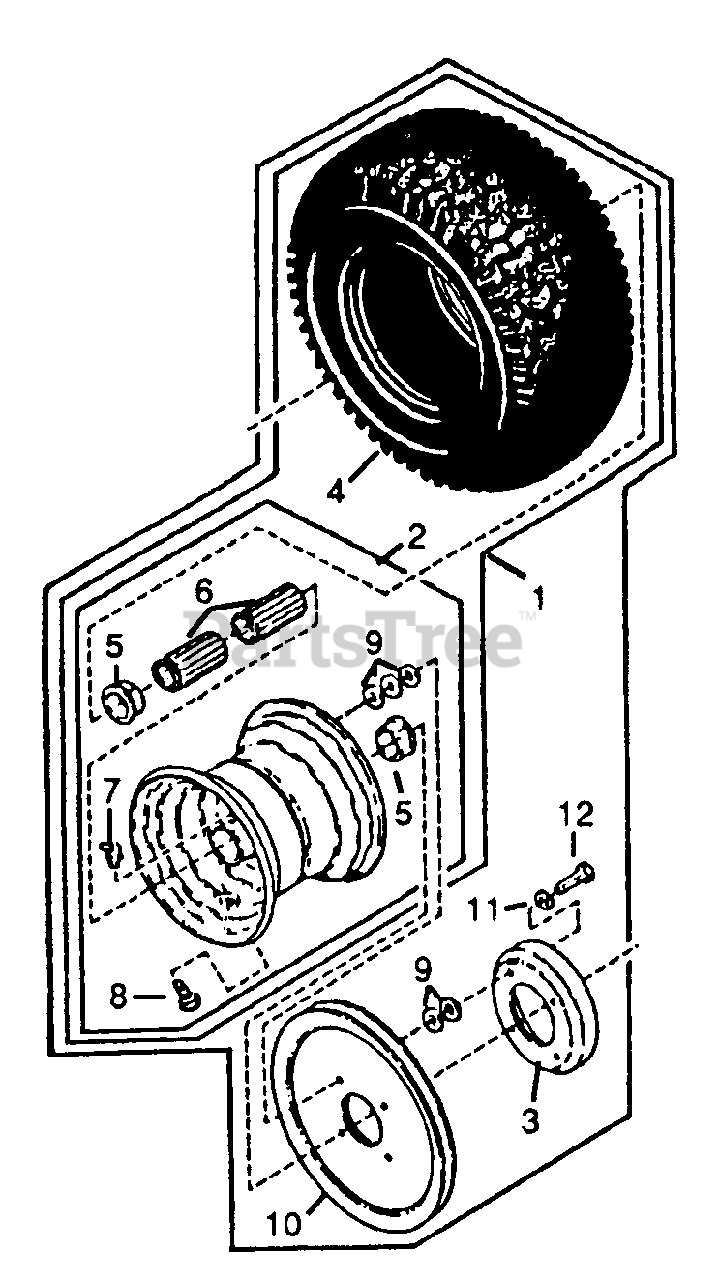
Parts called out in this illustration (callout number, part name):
1	Wheel Assembly, Pneumatic
2	Wheel Assembly
3	Brake Drum
4	Tire, Pneumabc, Tubeless
5	Retainer, Grafoil
6	Bearing, Roller
7	1/4' - 28 Zerk Fitting
8	Stem, Valve
9	5/16' Flat Washer
10	Pulley 7'
11	5/16' Spnng Lock Washer
12	5/16' -18 x 1-1/2' Hex. Hd. Cap Screw
